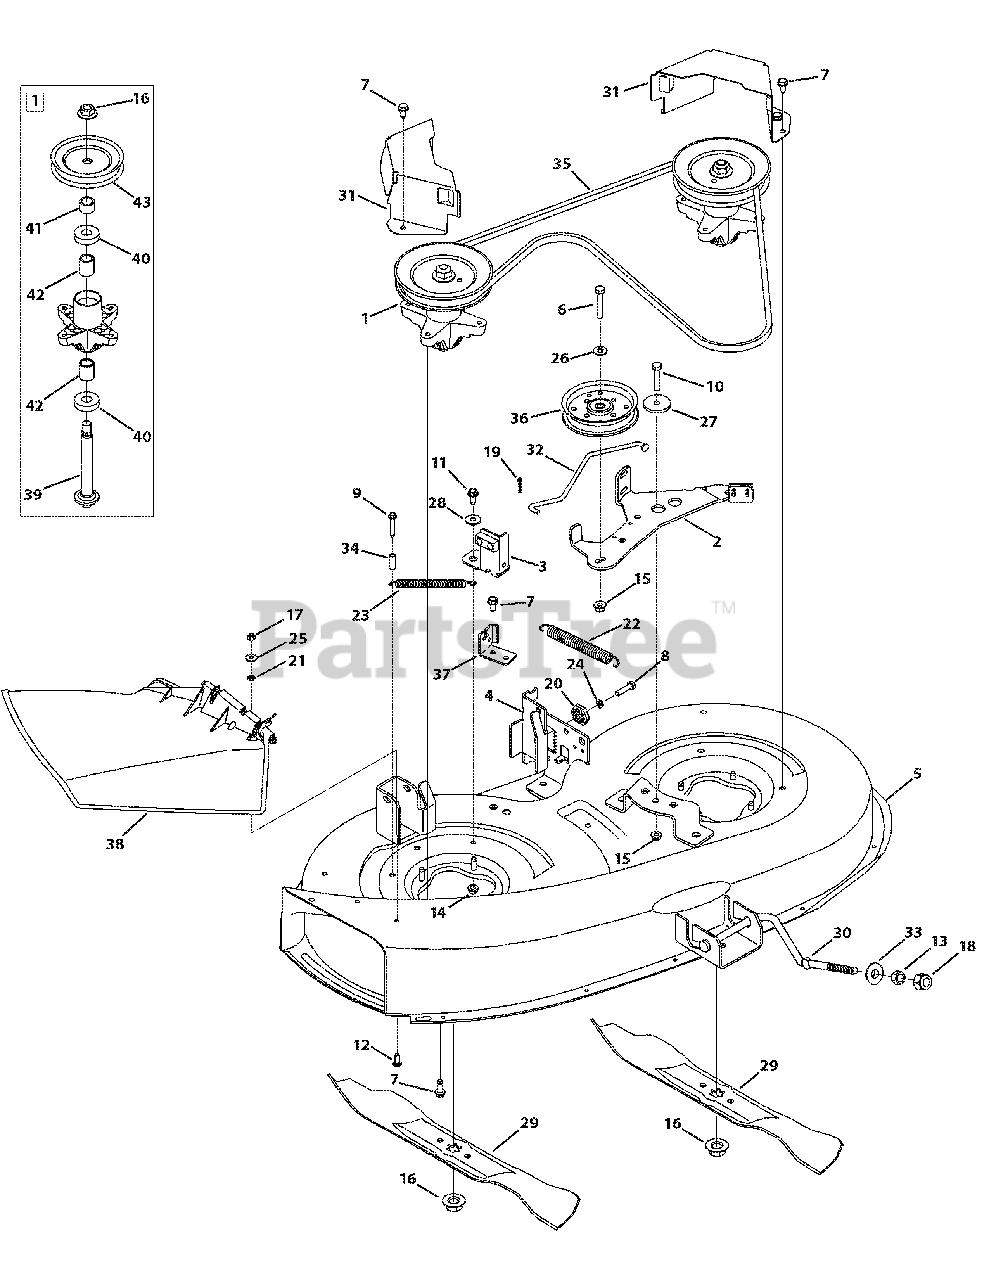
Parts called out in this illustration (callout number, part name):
1	5.75" Pulley Spindle Assembly
2	Deck Brake Assembly
3	Deck Brake Assembly
4	LH Deck Hanger Bracket
5	38" Deck Assembly - Red
6	Hex Screw, 3/8-16 x 1.75
7	Screw, 5/16-18 x .750
8	Hex Screw, 5/16-18 x 1.25
9	Screw, 1/4-20 x 1.50
10	Hex Screw, 3/8-16 x 1.25
11	Hex Screw, 5/16-18 x .75
12	Hex Screw, 1/4-20 x .75
13	Hex Nut, 1/2-13
14	Flangelock Nut, 5/16-18
15	Flangelock Nut, 3/8-16
16	Flange Nut, 5/8-18
17	Hex Nut, 1/4-20
18	Hexlock Nut, 1/2-13
19	Cotter Pin, .072 Diameter
20	Deck Adjuster Gear
21	Push Nut, .25 x .50
22	Extension Spring, .75 x 6.375
23	Extension Spring, .500 x 6.375
24	Lock Washer, 5/16
25	Bell Washer, .265 x .75 x .062
26	Flat Washer, .406 x .875 x .059
27	Shoulder Spacer, .8840 x .190
28	Shoulder Spacer, .5000 x .1475
29	3 in 1 Blade
30	38" Front Adjust Deck Rod
31	Belt Cover - Red
32	38" Brake Control Rod
33	Deck Lift, Pivot Cup
34	Spacer, .260 x .375 x 1.030
35	V Type Belt
36	Idler Pulley
37	Deck Engage Cable Bracket
38	Chute Assembly 38"
39	Spindle Shaft, 5.50
40	Ball Bearing, .787ID x 1.85 OD x .551
41	Spacer, .820 x 1.150 x .480 LG
42	Spacer, .80 x 1.10 x 1.322 LG
43	Deck Pulley, 5.75
